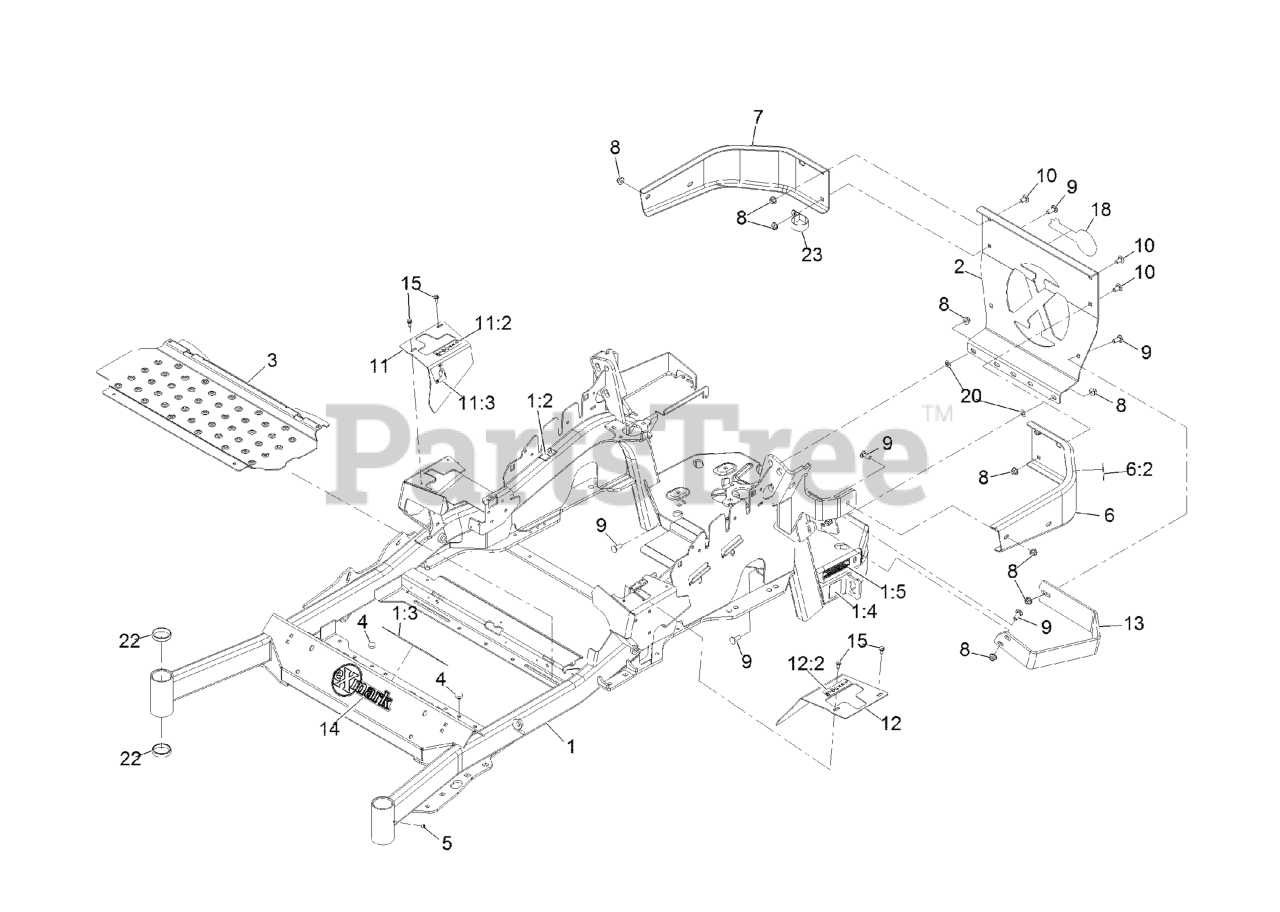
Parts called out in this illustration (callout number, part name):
1	MAINFRAME ASM
1:2	DECAL-WARNING
1:3	DECAL-DANGER
1:4	DECAL-HAZARD, PINCHED FINGER
1:5	DECAL-ARRESTOR, SPARK
2	PLATE,REAR GUARD
6	LH BUMPER ASM
6:2	DECAL-WARNING
7	BUMPER-RH
8	NUT-HF, NI
9	SCREW-CARR
10	SCREW-CARR
11	RH MOTION CONTROL COVER ASM
11:2	DECAL-CONTROL, MOTION
11:3	DECAL-PARK BRAKE, CE
12	LH MOTION CONTROL COVER ASM
12:2	DECAL-CONTROL, MOTION
13	GUARD-MUFFLER
14	DECAL-EXMARK
15	SCREW-HWH
20	NUT-PUSH
22	CUP-BEARING
23	CLAMP-R
